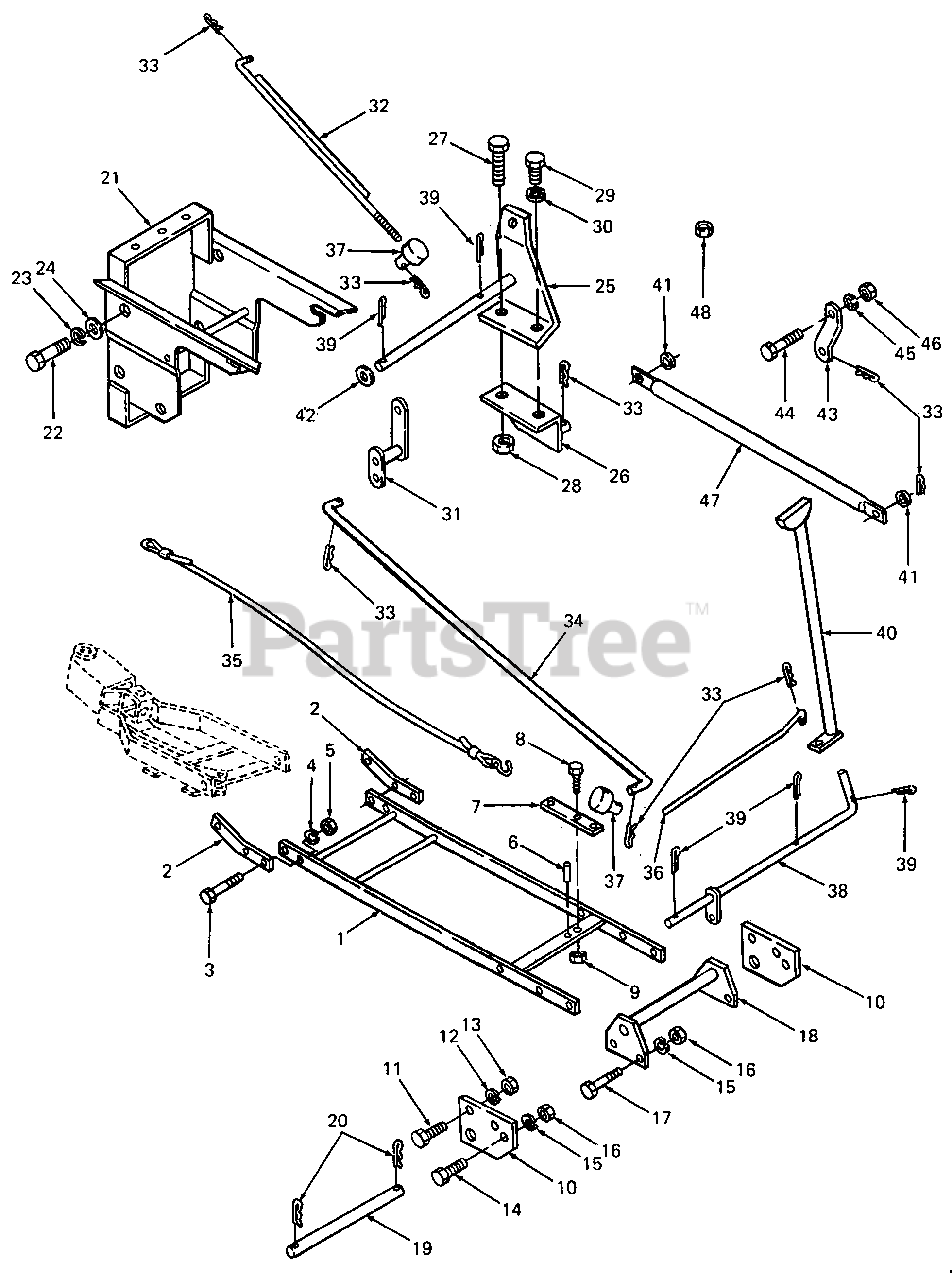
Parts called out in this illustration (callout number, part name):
1	Frame, Mounting
2	Strap, Front Mounting
3	Screw, Hex Cap, 1/2-13 X 1.5 Lg GR5
4	Washer, Lock, 1/2
5	Nut, Hex, 1/2-13
7	Strap, Pivot Control
8	Screw, Hex Cap, 3/8-16 X 1.0 Lg GR5
9	Nut, Hex Center Lock, 3/8-16
10	Plate, Anchor
11	Screw, Hex Cap, 3/8-16 X 1.0 Lg GR5
12	Washer, Lock, 3/8
13	Nut, Hex, 3/8-16
14	Screw, Hex Cap, 1/2-13 X 1.25 Lg GR5
15	Washer, Lock, 1/2
16	Nut, Hex, 1/2-13
17	Screw, Hex Cap, 1/2-13 X 1.5 Lg GR5
18	Frame, Rear Mounting
19	Pin, Locating
20	Pin, Quick Attach
21	Frame, Front Mounting
22	Screw, Hex Cap, 1/2-13 X 1.5 Lg GR5
23	Washer, Lock, 1/2
24	Washer, Flat, .531 X 1.25 X .100 Thk
25	Arm Assembly, Lift
26	Extension, Lift
27	Screw, Hex Cap
28	Nut, Hex Jam, 1/2-13
29	Screw, Hex Patch Cap, 1/2-13 X 1.0 Lg GR5
30	Washer, Lock, 1/2
31	Crank Assembly, Bell
32	Rod Assembly, Control
33	Pin, Quick Attach
34	Rod, Pivot
35	Cable, Pivot Control
36	Rod, Pivot Control
38	Arm Assembly, Pivot
39	Pin, Cotter, 3/6 Dia X 1.75 Lg
40	Handle Assy, Pivot Control
41	Washer, Flat, .500 X 1.0 X .060 Thk
42	Washer, Flat, .812 X 1.5 X .134 Thk
43	Strap, Cross Shaft Support
44	Screw, Hex Cap, 1/2-13 X 1.25 Lg GR5
45	Washer, Lock, 1/2
46	Nut, Hex, 1/2-13
